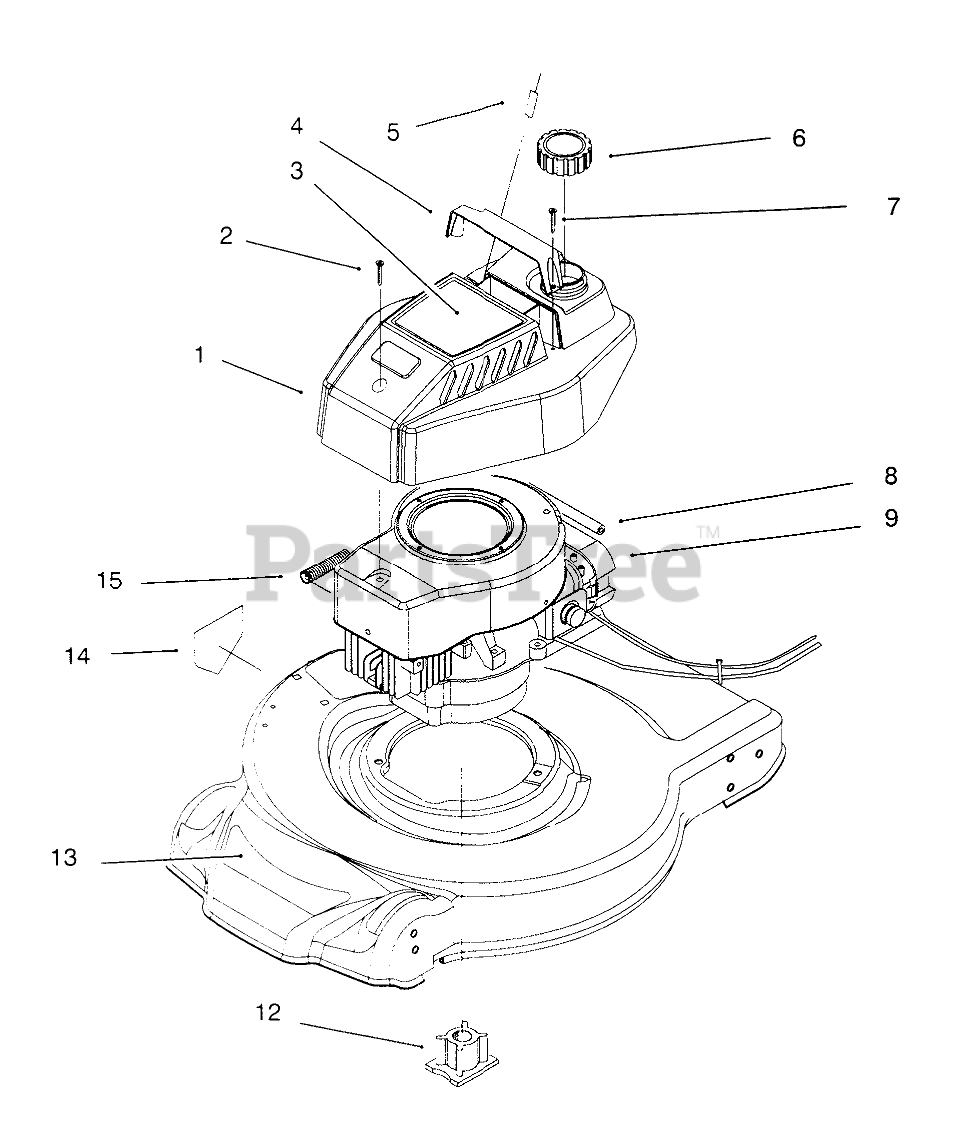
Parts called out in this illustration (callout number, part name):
1	TANK/SHROUD
2	SCREW
3	OBS EXCEPT FOR SERVICE DECAL - ENGINE
4	STRAP - TANK
5	STOP-ROPE
6	GAS CAP ASSEMBLY
7	SCREW-PPH
8	HOSE-FUEL
9	Engine (Model No. 20441 Only)
12	BLADE RETAINER
13	DECAL - DECK
14	DECAL-DANGER
15	SPRING-COMPRESSION
